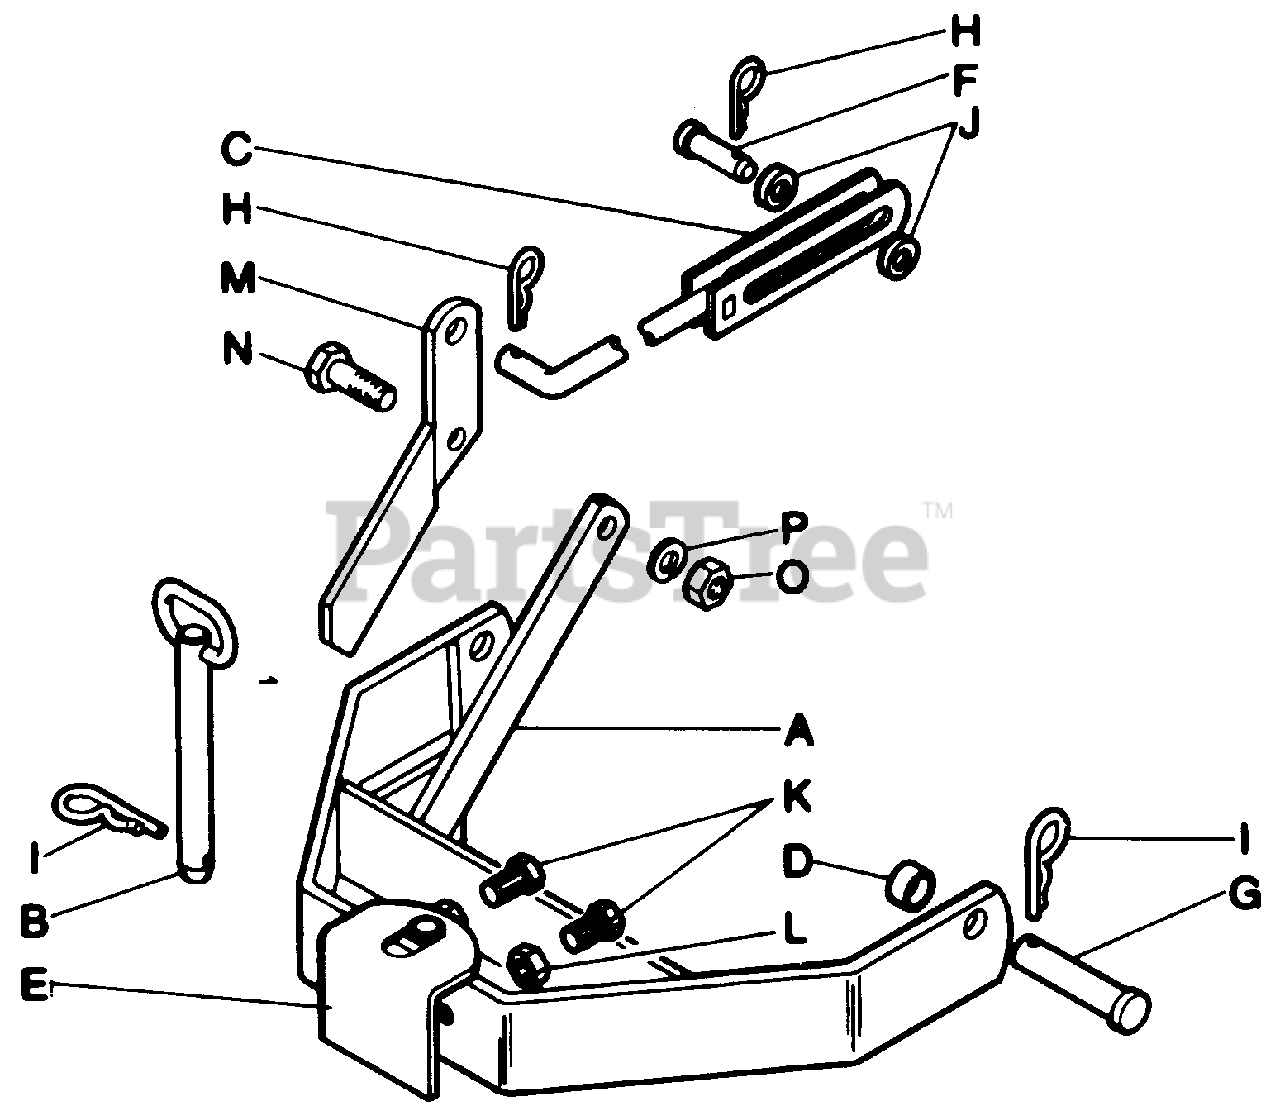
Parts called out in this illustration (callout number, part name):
A	Sleeve Hitch Assembly
B	Hitch Pin Assembly
C	Lift Rod Assembly
D	Spacer
E	Stabilizer Plate
F	Clevis Pin
G	Clevis Pin
H	Spring Clip
I	Spring Clip
J	Washer, 7/16 Flat Plated
K	Cap Screw, Hex Hd. 1/2-20 x 1-1/2 Plated Grade 5
L	Nut, Hex Jam 1/2-20 Plated
M	Lift Arm Extension Assembly
N	Cap Screw, Hex Hd. 1/2-13 x 1-1/2 Plated Grade 5
O	Nut, Hex 1/2-13 Plated
P	Washer, Spring Lock 1/2 Plated
